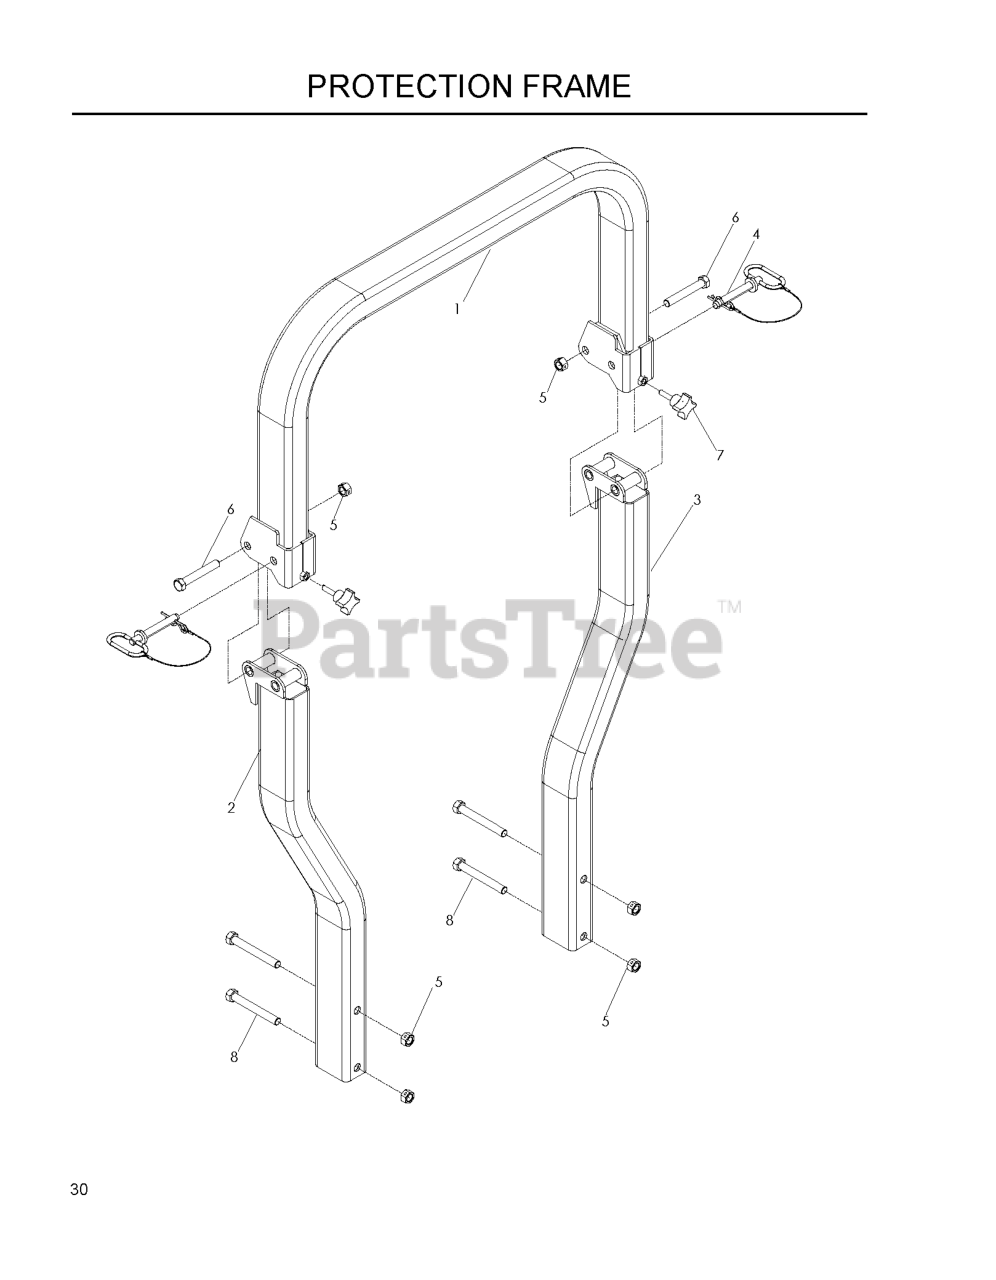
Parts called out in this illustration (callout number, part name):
2	SIDE TUBE, RT
3	SIDE TUBE, LT
4	PIN, 1/2" W/LANYARD
5	NUT 1/2-13 HEX CNTRLK GR 5 ZD
6	HCS 1/2C X 3 1/4
7	KNOB W/STUD 3/8-16 X 1.5
8	HCS 1/2-13 X 4 GR 5 ZD
